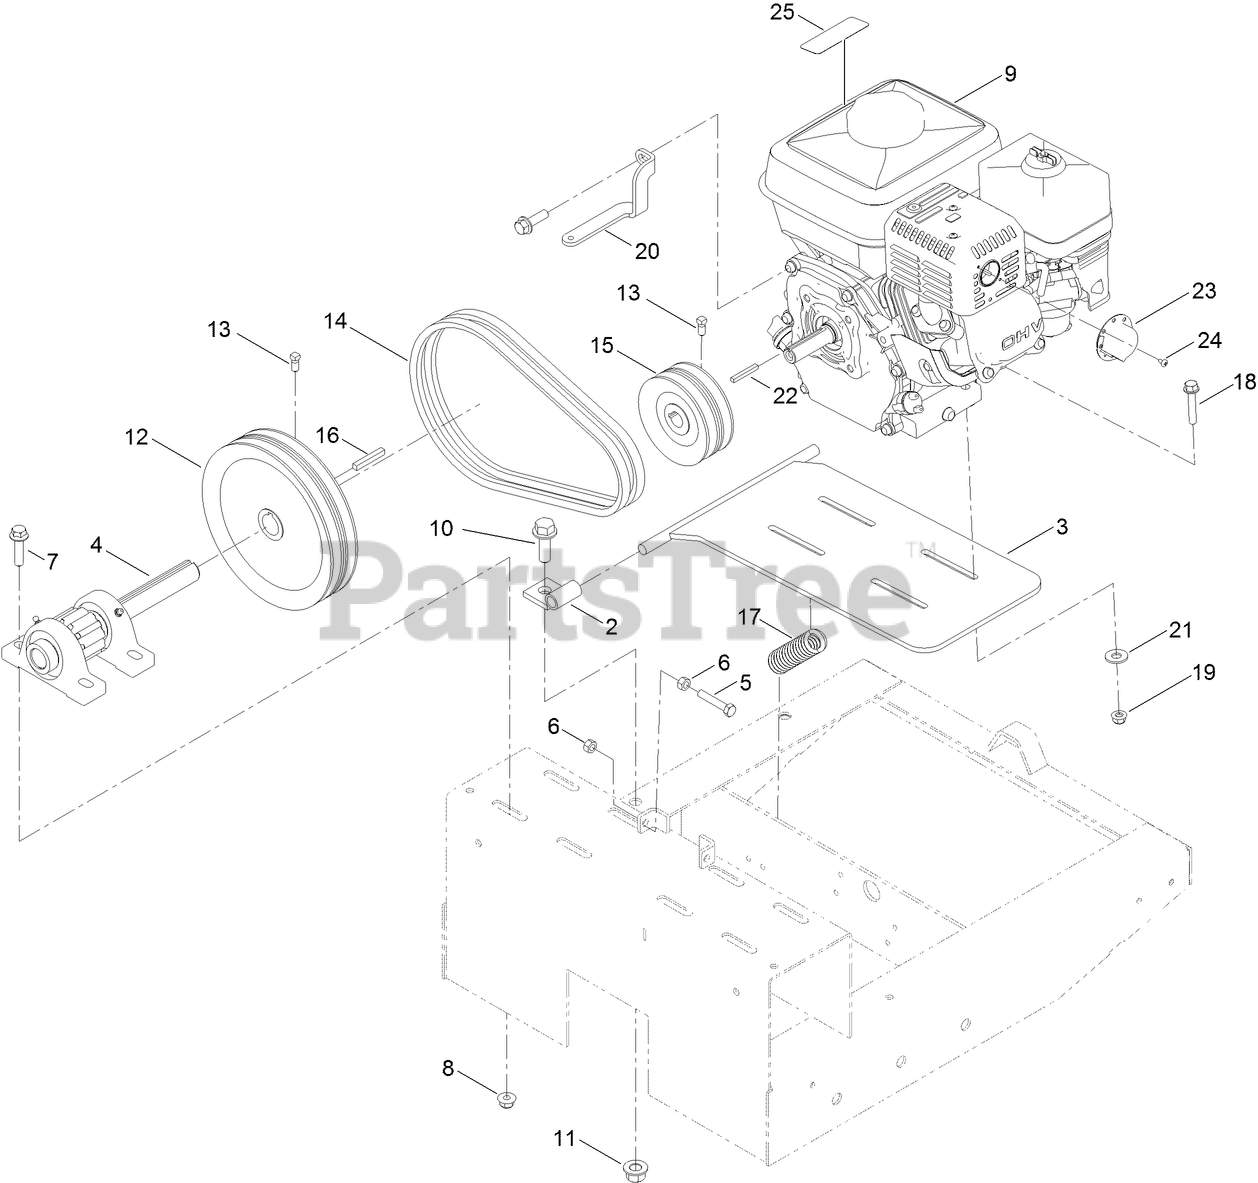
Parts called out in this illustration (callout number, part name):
2	MOUNT-MOTOR
3	BASE-MOTOR
4	PINION ASM
5	SCREW-HH
6	NUT-HEX
7	SCREW-HHF
8	NUT-HF, NI
10	SCREW-HHF
11	NUT-LOCK
12	SHEAVE
13	SCREW-SET
14	BELT-V
15	SHEAVE
16	KEY-SQUARE
17	SPRING
18	SCREW-HWH
19	NUT-HF, NI
20	GUIDE-BELT
21	WASHER-FLAT
22	KEY-SQUARE
23	DEFLECTOR
24	SCREW-SELF TAPPING
25	DECAL-WARNING, ETHANOL
